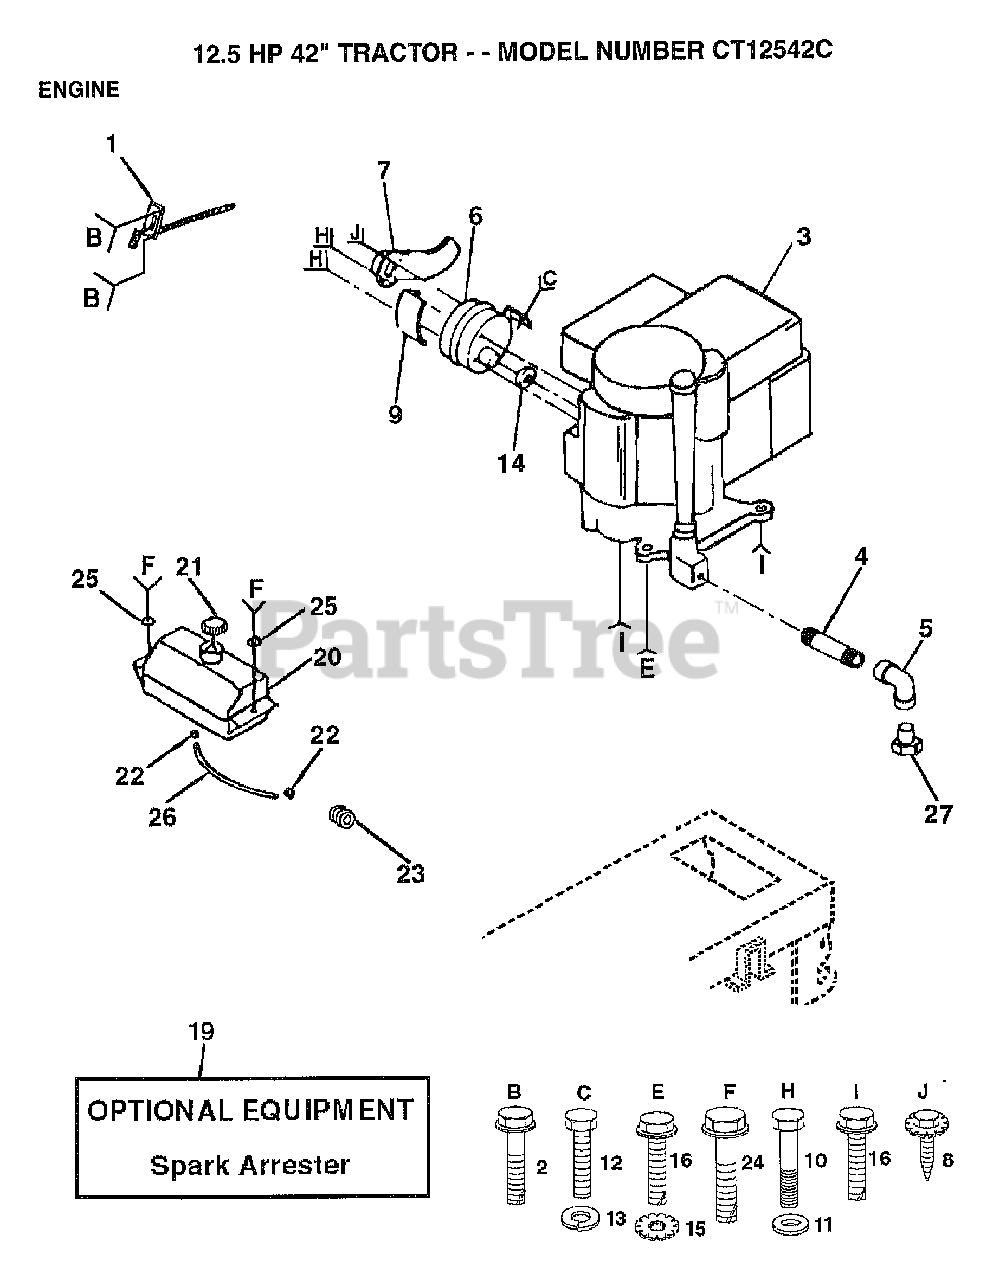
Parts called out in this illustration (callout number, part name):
1	THROTTLE CONTROL
2	SCREW LT
4	PIPE NIPPLE
5	ELBOW
6	MUFFLER LTV
7	DEFLECTOR MUFFLER
9	SHIELD HEAT LTV
10	"BOLT,HEX"
11	WASHER T
12	BOLT
13	LOCKWASHER
15	LOCKWASHER
16	SCREW
20	TANK.FUEL.LT.
22	HOSE CLAMP
24	SCREW HEX CRT
25	WASHER
26	FUEL LINE T
